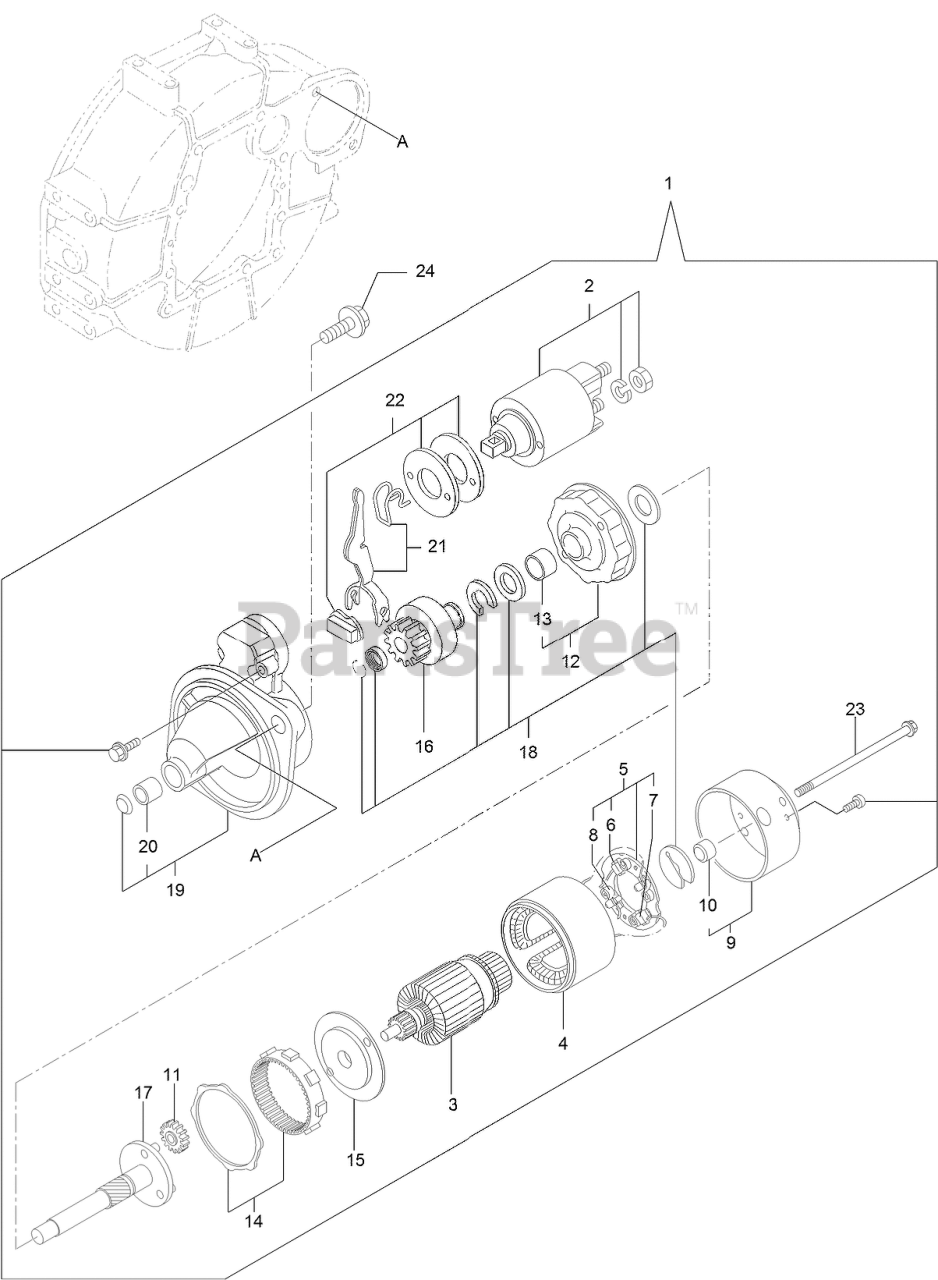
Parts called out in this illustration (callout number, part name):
1	STARTER ASM
2	SWITCH ASM
3	Armature ASM
4	Yoke ASM
5	Brush Holder ASM
7	BRUSH SET
9	Cover ASM
12	Bracket
13	Bracket
15	Bracket
16	PINION ASM
18	Washer Set
19	Case ASM
20	Metal-Starter
21	Lever Set
22	Dust Cover ASM
23	BOLT-THROUGH
